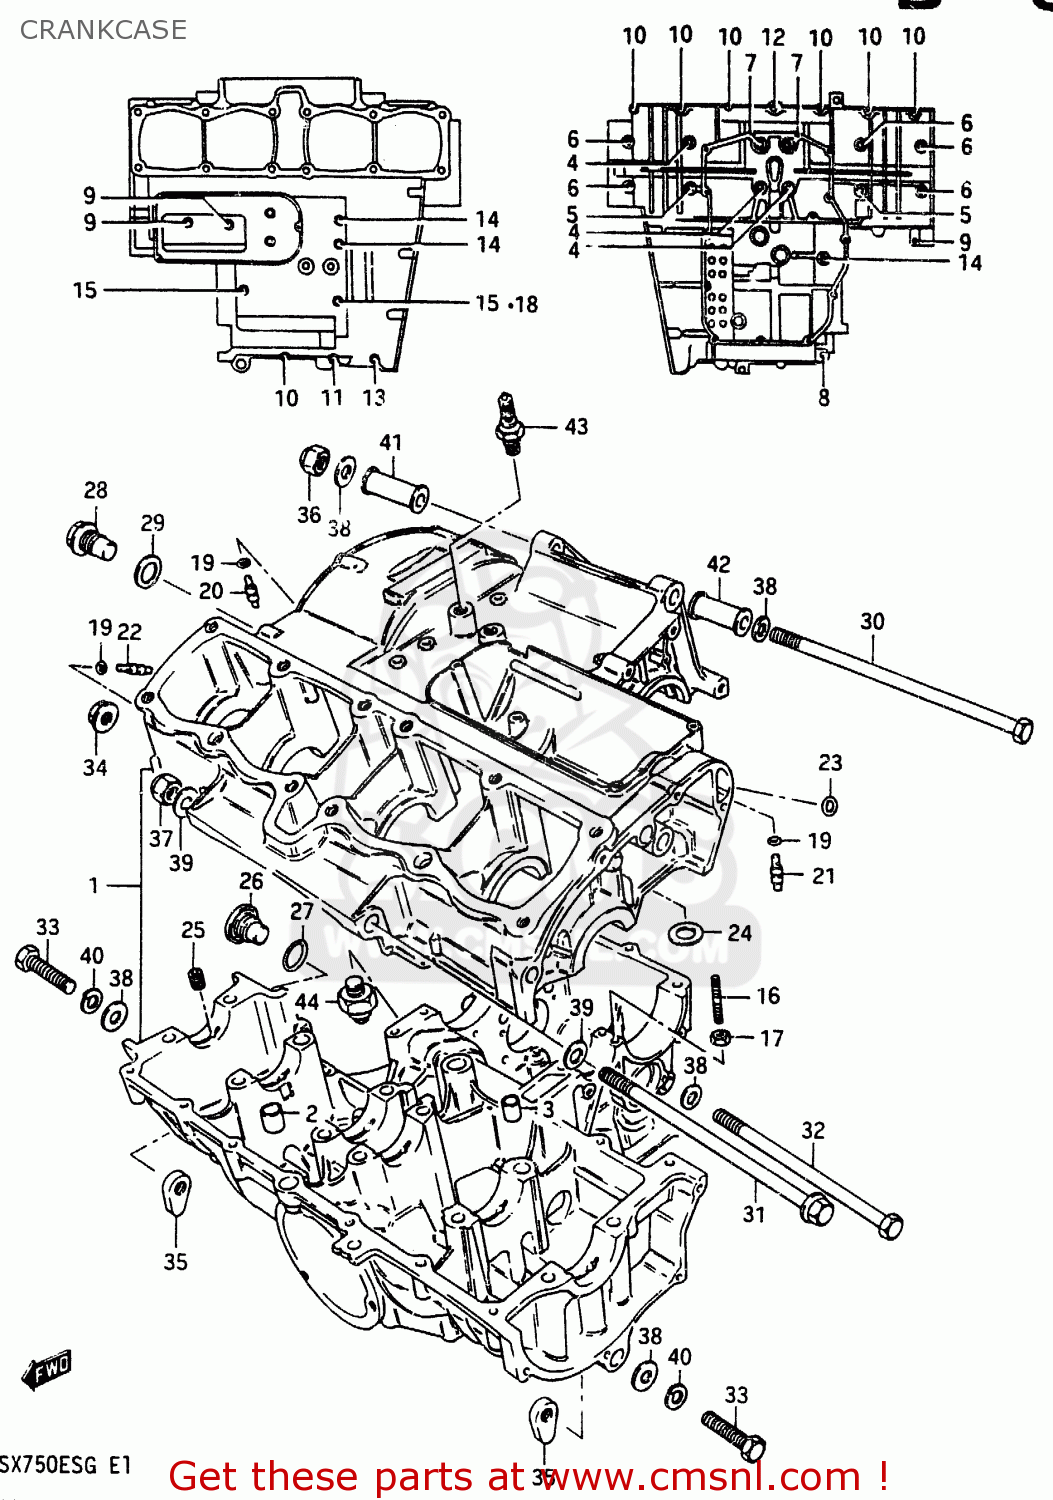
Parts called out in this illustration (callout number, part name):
1	CRANKCASE ASSEMBLY
2	PIN(10.4X13X22)
3	PIN (11X20)(SUS)
4	BOLT(8X120)
5	BOLT(8X135)
6	BOLT
7	BOLT
8	BOLT 8X60
9	BOLT 6X35
10	BOLT
11	BOLT
12	BOLT 6X50
13	BOLT 6X55
14	BOLT
15	BOLT (5X95)
16	STUD BOLT (6X45)
17	NUT
18	GASKET(6.2X13X1.2) (NAS)
19	O RING(D:1.2,ID:4)
20	JET,OIL GALLERY
21	JET(8)
22	JET,OIL
23	O RING(D:3.2,ID:12.9)
24	WASHER,THRUST
25	JET,AIR
26	PLUG
27	O RING(D:2.4,ID:16.8)
28	PLUG
29	GASKET(14X19.2X2) (NAS)
30	BOLT 10X255
31	BOLT 10X205
32	BOLT
33	BOLT
34	NUT 10MM
35	NUT
36	NUT
37	NUT
38	WASHER
39	WASHER (10.5X22X2.3)
40	LOCK WASHER
41	SPACER,ENGINE MOUNT
42	SPACER,ENGINE MOUNT(L:50)
43	GAUGE ASSEMBLY,OIL TEMPERATURE
44	SWITCH ASSEMBLY
